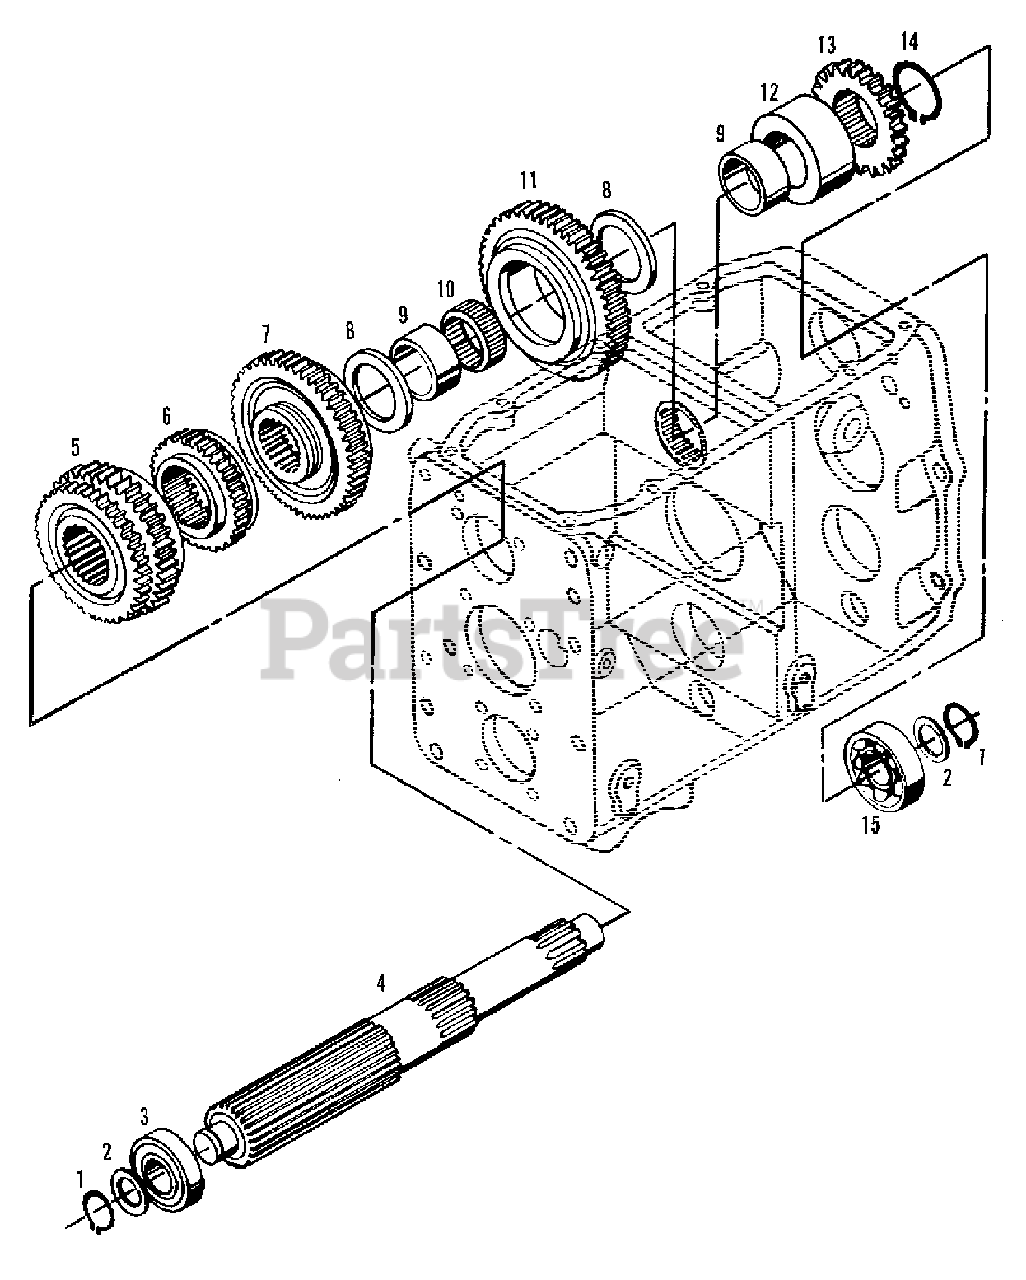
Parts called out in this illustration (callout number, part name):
1	RING, M25 snap - external
2	WASHER, thrust
3	BEARING ASSEMBLY (Incl. SNAP RING)
4	SHAFT, counter
5	GEAR, 3rd - 4th - countershaft
6	GEAR, reverse - countershaft
7	GEAR, 2nd - countershaft
8	WASHER, thrust
9	RING, inner
10	BEARING, needle
11	GEAR, 1st - countershaft
12	COLLAR, distance
13	GEAR, 23 teeth - countershaft
14	RING, M45, snap - external
15	BEARING, ball
